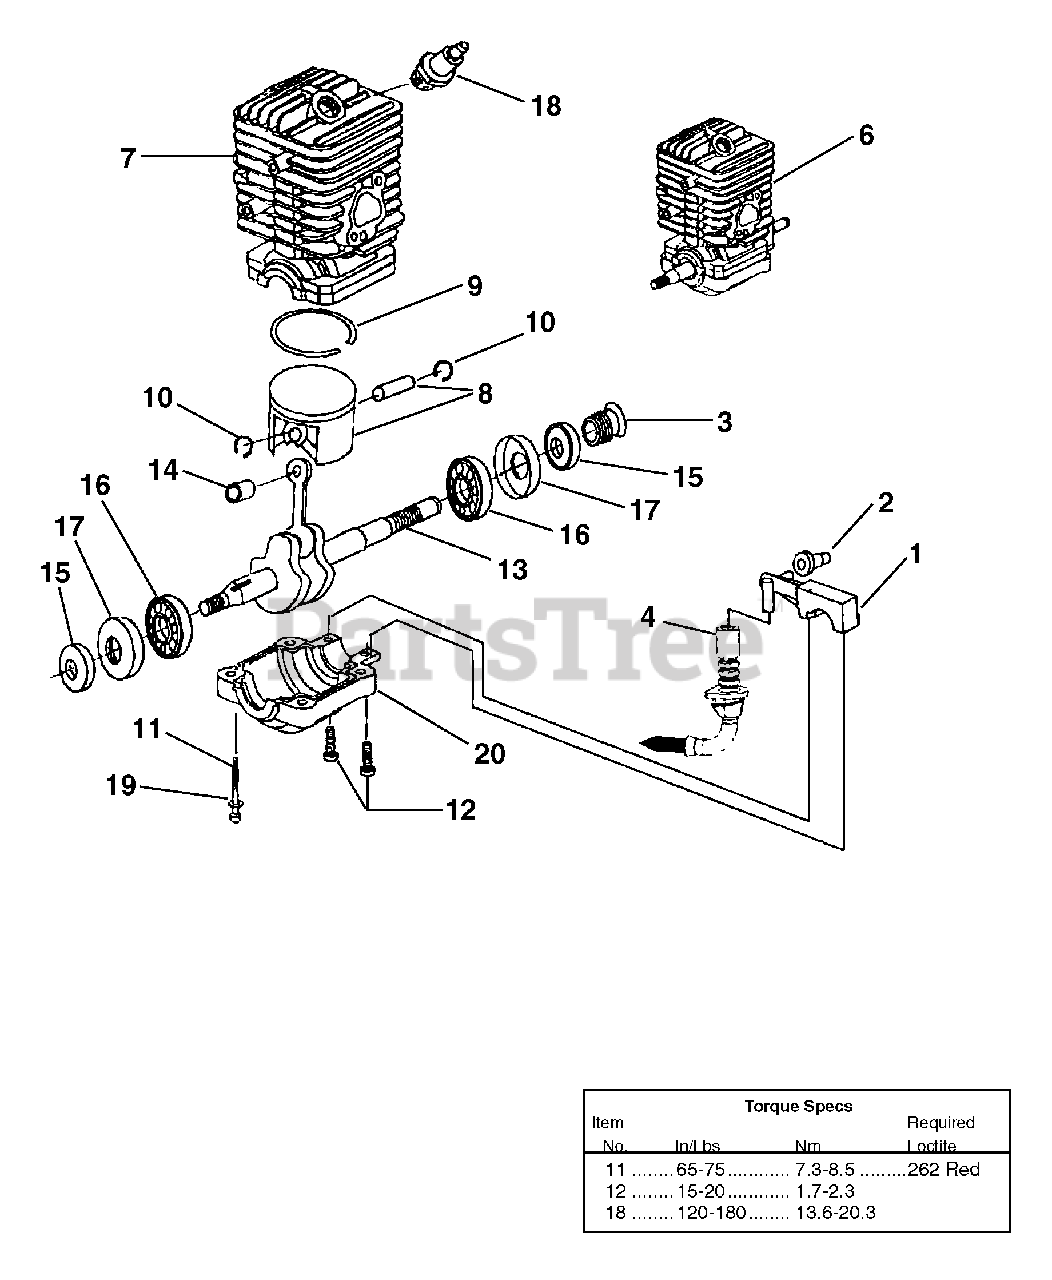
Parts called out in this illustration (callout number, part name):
1	Oil Pump Kit
2	Grommet, Oil Outlet
3	Left Hand Worm
4	Oil Intake Tube w/Filter
6	Short Block, Complete (33cc)
7	Cylinder Kit (33cc)
8	Piston & Pin (33cc)
9	Piston Ring
10	Ring, Retaining
11	Screw, Cap-Socket Hd. (10-24 x 2")
12	Screw, Pan Hd., Plastite (8-32 x5/8" )
13	Crankshaft & Rod Assembly
14	Bearing, Needle
15	Shaft Seal
16	Bearing & Rubber Case
17	Rubber Case
18	Spark Plug
19	Washer
20	Lower Crankcase
